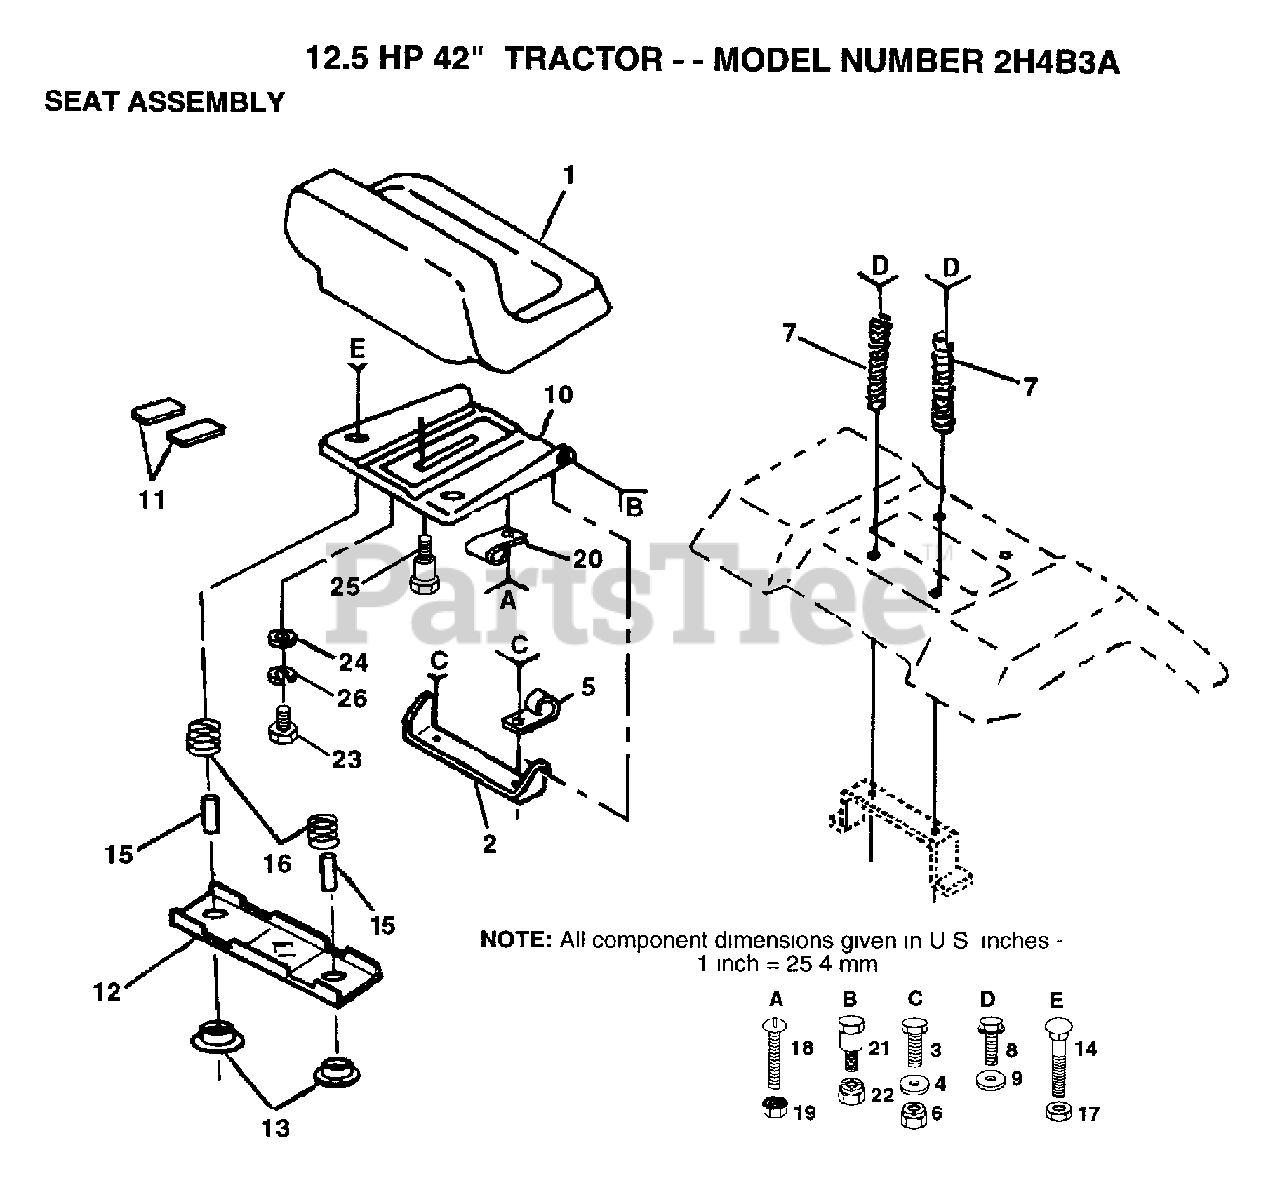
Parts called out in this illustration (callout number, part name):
4	WASHER PM
5	CLIP T
7	SPRING COMPRESSIO
8	SCREW GTV
9	WASHER
11	STRIP FORM
12	BRKT SWITCH
13	BUSHING
15	SPLIT SPACER
16	SPRING
19	"NUT,KEPS"
23	BOLT
24	WASHER
25	"BOLT,SHOULDER"
26	LOCKWASHER
